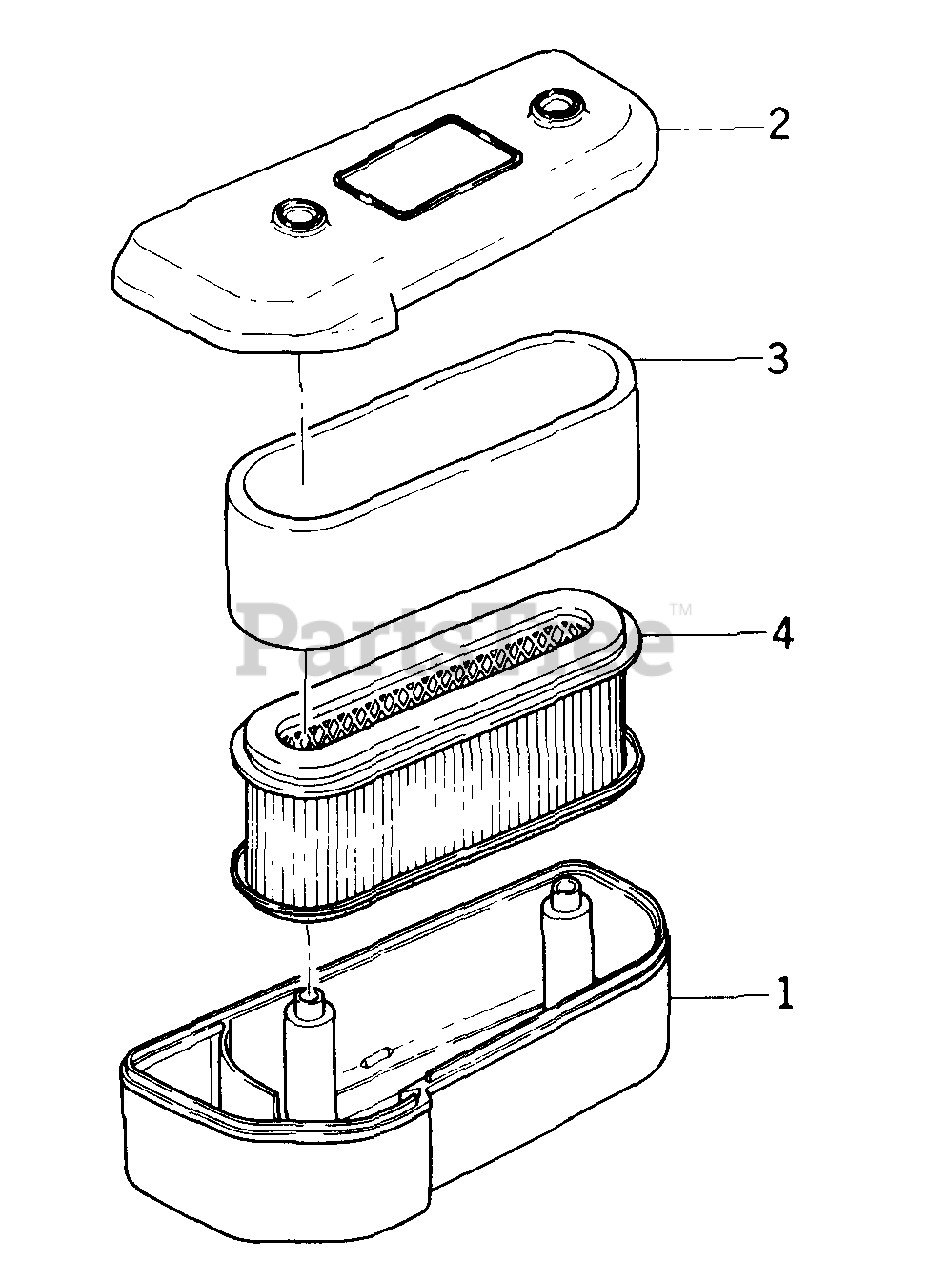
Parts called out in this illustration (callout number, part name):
1	CASE, air filter
2	CAP, air filter
3	ELEMENT, air filter
4	ELEMENT, air filter
